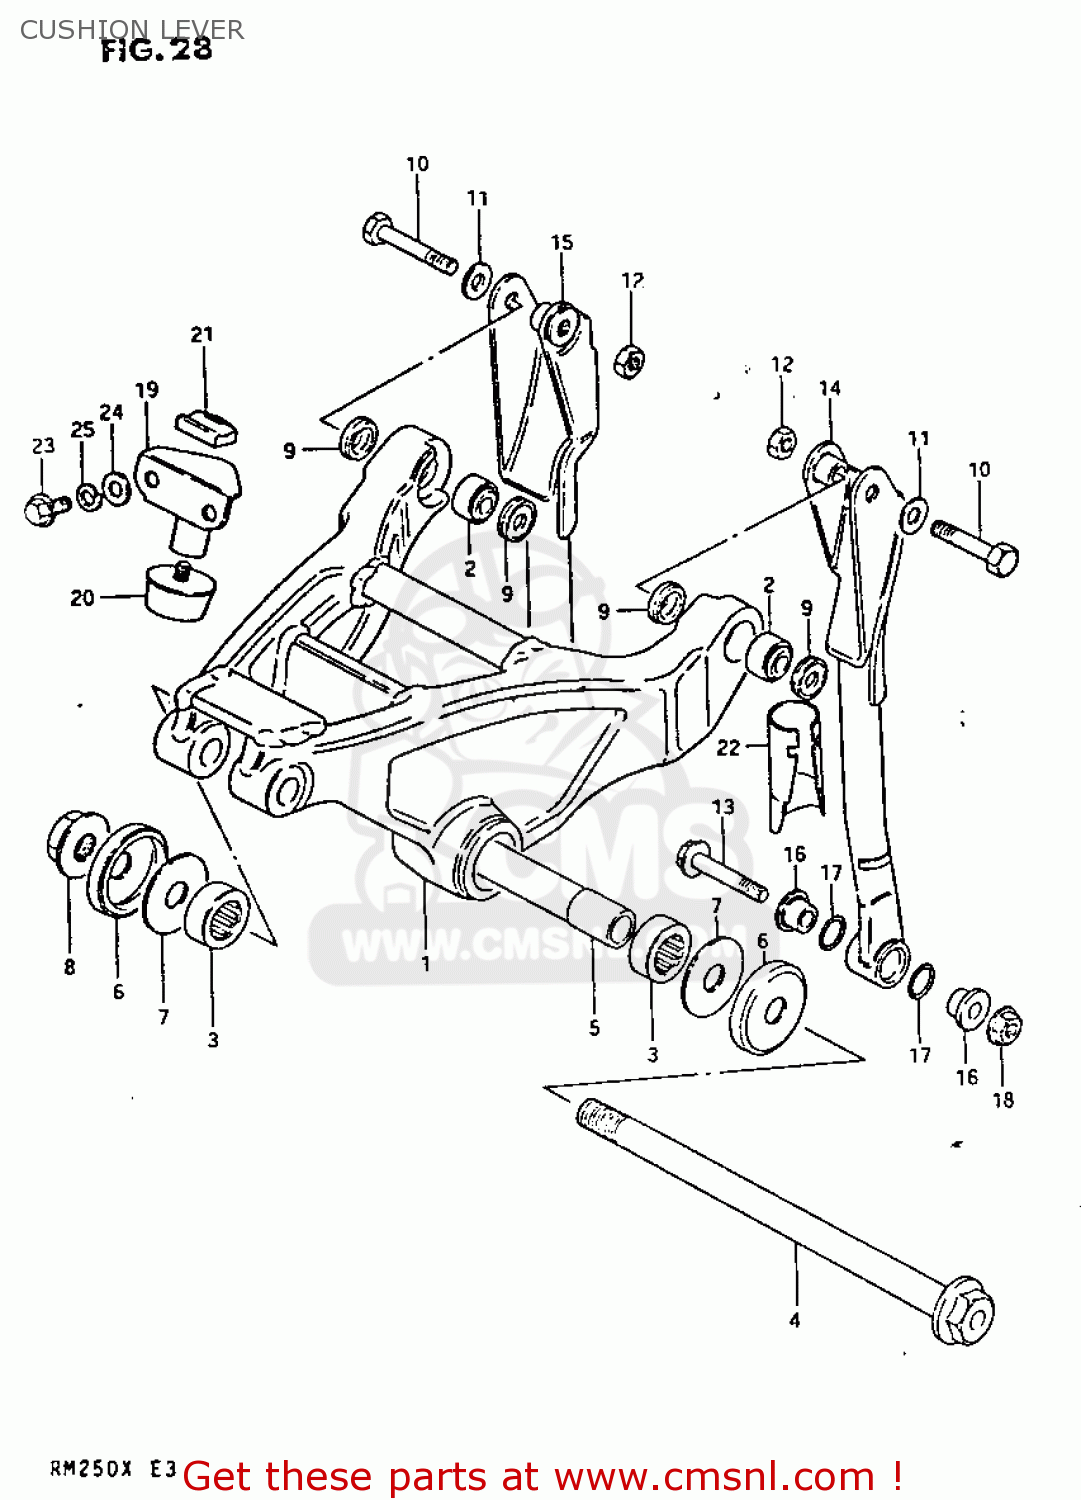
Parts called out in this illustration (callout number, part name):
1	LEVER SET,REAR CUSHION
2	BEARING(8X18X11)
3	BEARING(17X26X20)
4	SHAFT,REAR CUSHION LEVER
5	SPACER,REAR CUSHION LEVER
6	DUST SEAL
7	WASHER(12X35X2)
8	NUT 12MM
9	10
10	BOLT 8X38
11	WASHER
12	NUT
13	BOLT(8X45)
14	ROD,REAR CUSHION LEVER
15	BOLT,REAR CUSHION LEVER
16	SPACER,RR CUSHION ROD LWR
17	O RING(D:1.9,ID:13)
18	NUT
19	STOPPER,TENSION
20	RUBBER,TENSION STOPPER
21	SUPPORT RUB TENS
22	PROTECTOR,REAR CUSHION R
23	BOLT
24	WASHER
25	WASHER,LOCK
